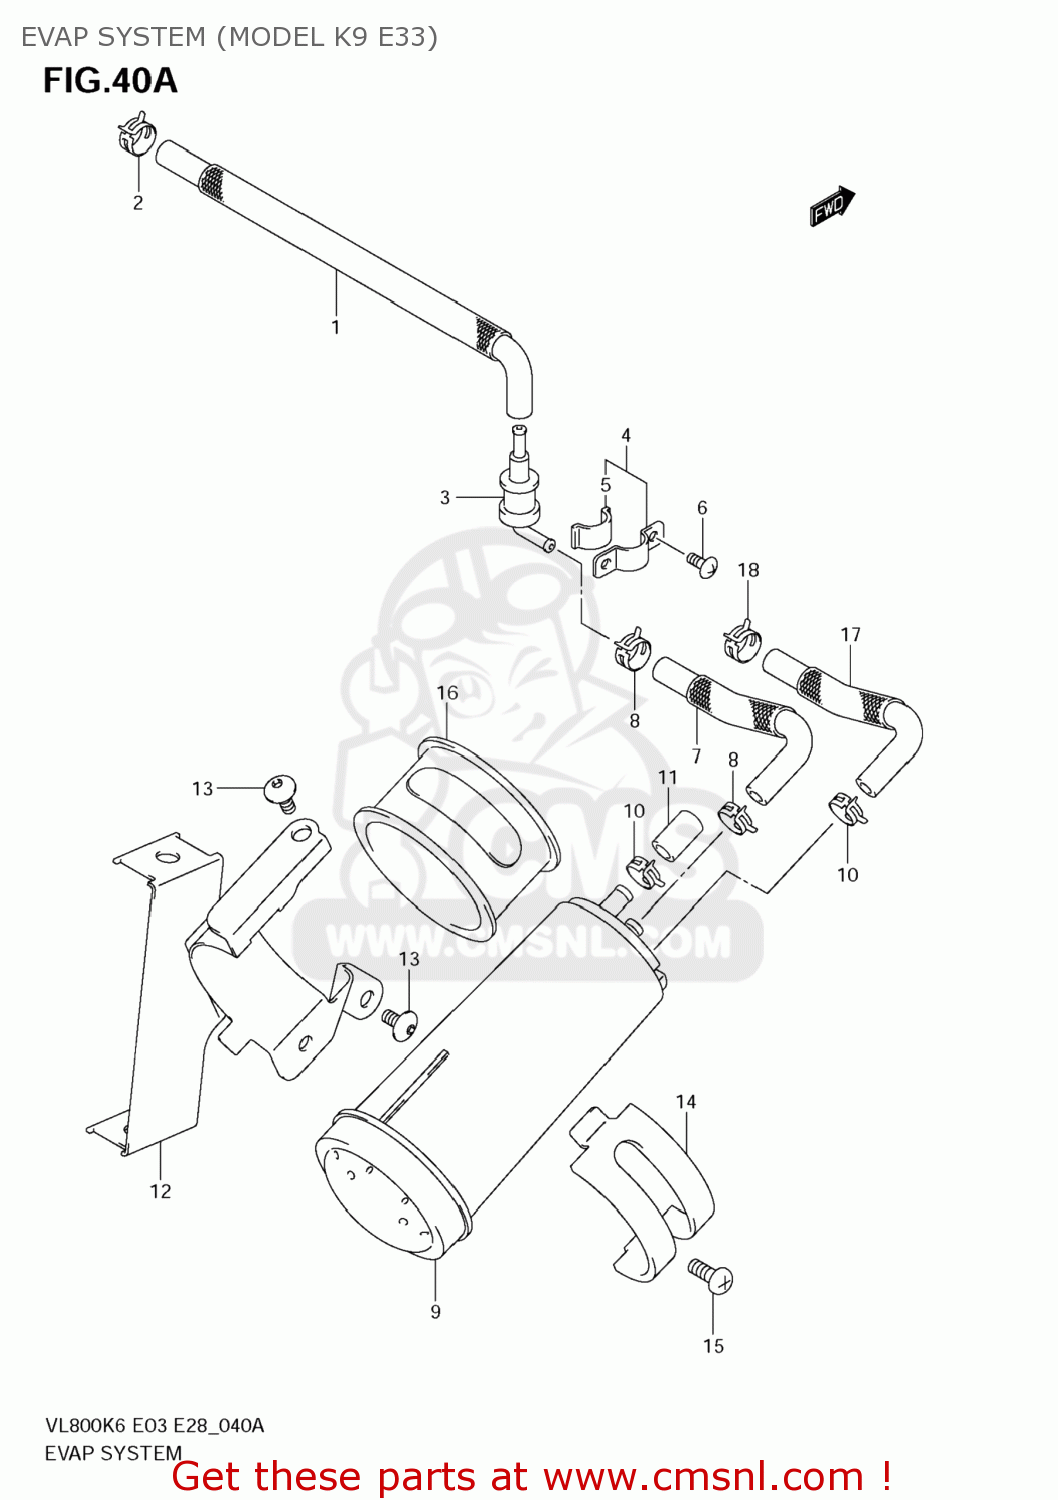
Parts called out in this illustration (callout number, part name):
1	HOSE,TANK & BREATHER VALVE
2	CLIP
3	VALVE,FUEL TANK BREATHER
4	PLATE,FUEL TANK BREATHER NO.2
5	CUSHION
6	SCREW
7	HOSE,BREATHER VALVE & CANISTER
8	CLIP
9	CANISTER SET
10	CLIP
11	CAP,OD:11.5
12	BRACKET,FI CONTROL UNIT
13	SCREW(6X12)
14	HOLDER,CANISTER
15	SCREW
16	CUSHION,CANISTER
17	HOSE,CSTR PURGE
18	CLIP
